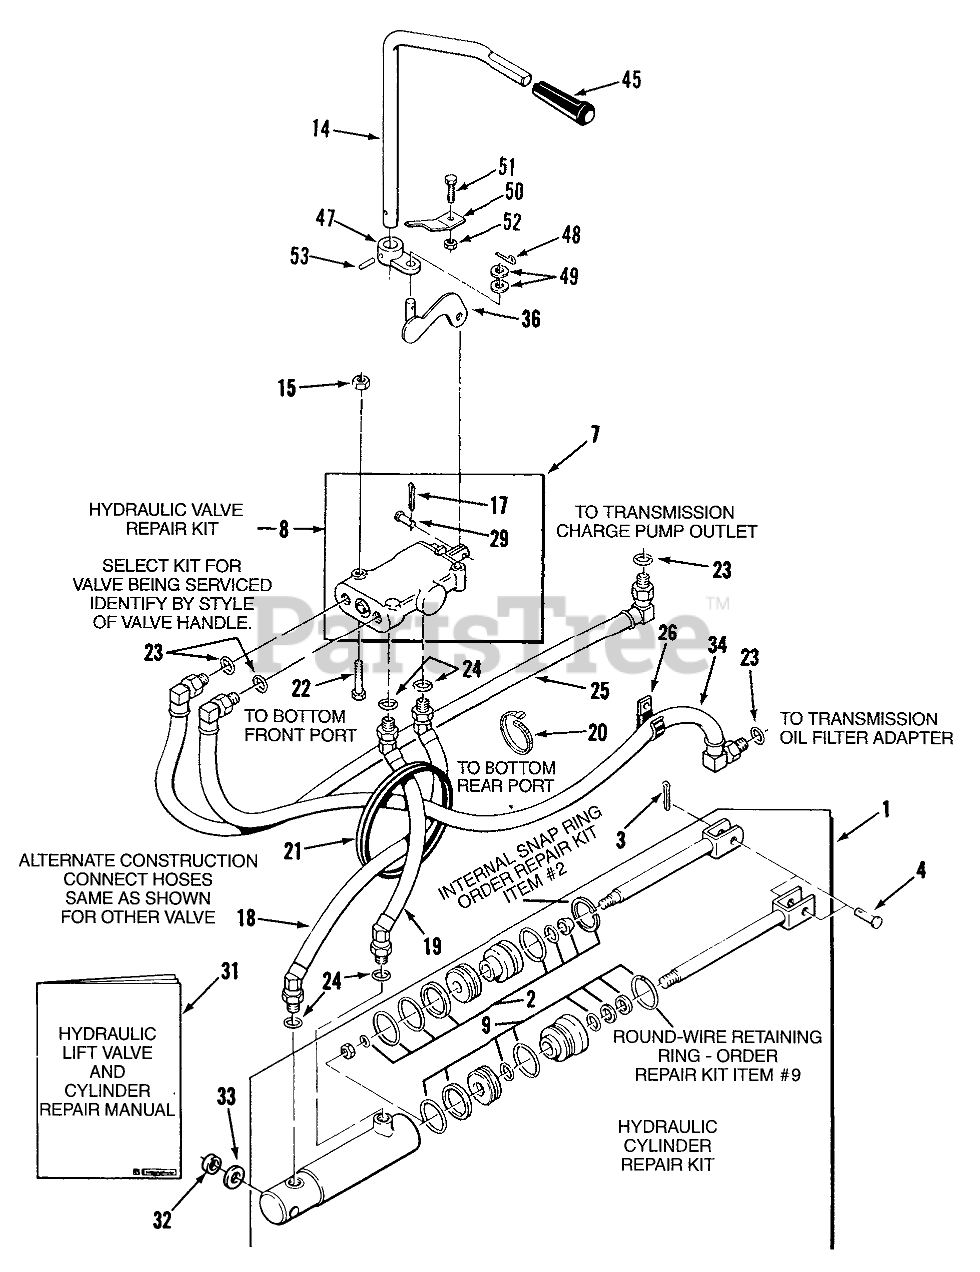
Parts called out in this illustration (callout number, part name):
1	ASS'Y-CYLINDER
2	S/A O-RING&GASKET AS
4	CLEVIS PIN
7	ASS'Y-VALVE
8	S/A 110068 VALVE
9	S/A 108872 HYD CYL
14	Valve Handle
15	Nut
17	Cotter Pin
18	Hose ASM-Hydraulic
19	Hose ASM-Hydraulic
20	PLASTIC TIE
21	GROMMET
22	Bolt 1/4-20 x 2
23	0-Ring
24	O RING
26	CLIP
29	Pin
31	Repair Manual
32	Spacer
33	WASHER
34	ASSY HYD HOSE
36	WLDMT-LIFT BAR B
45	KNOB-HYDRAULIC LIFT
47	ARM-CONTROL
48	Cotter Pin
49	WASHER 5/16 SAE
50	BRACKET-CONTROL R B
51	Bolt
52	Nut
53	SPIROL PIN 7/32X7/8
